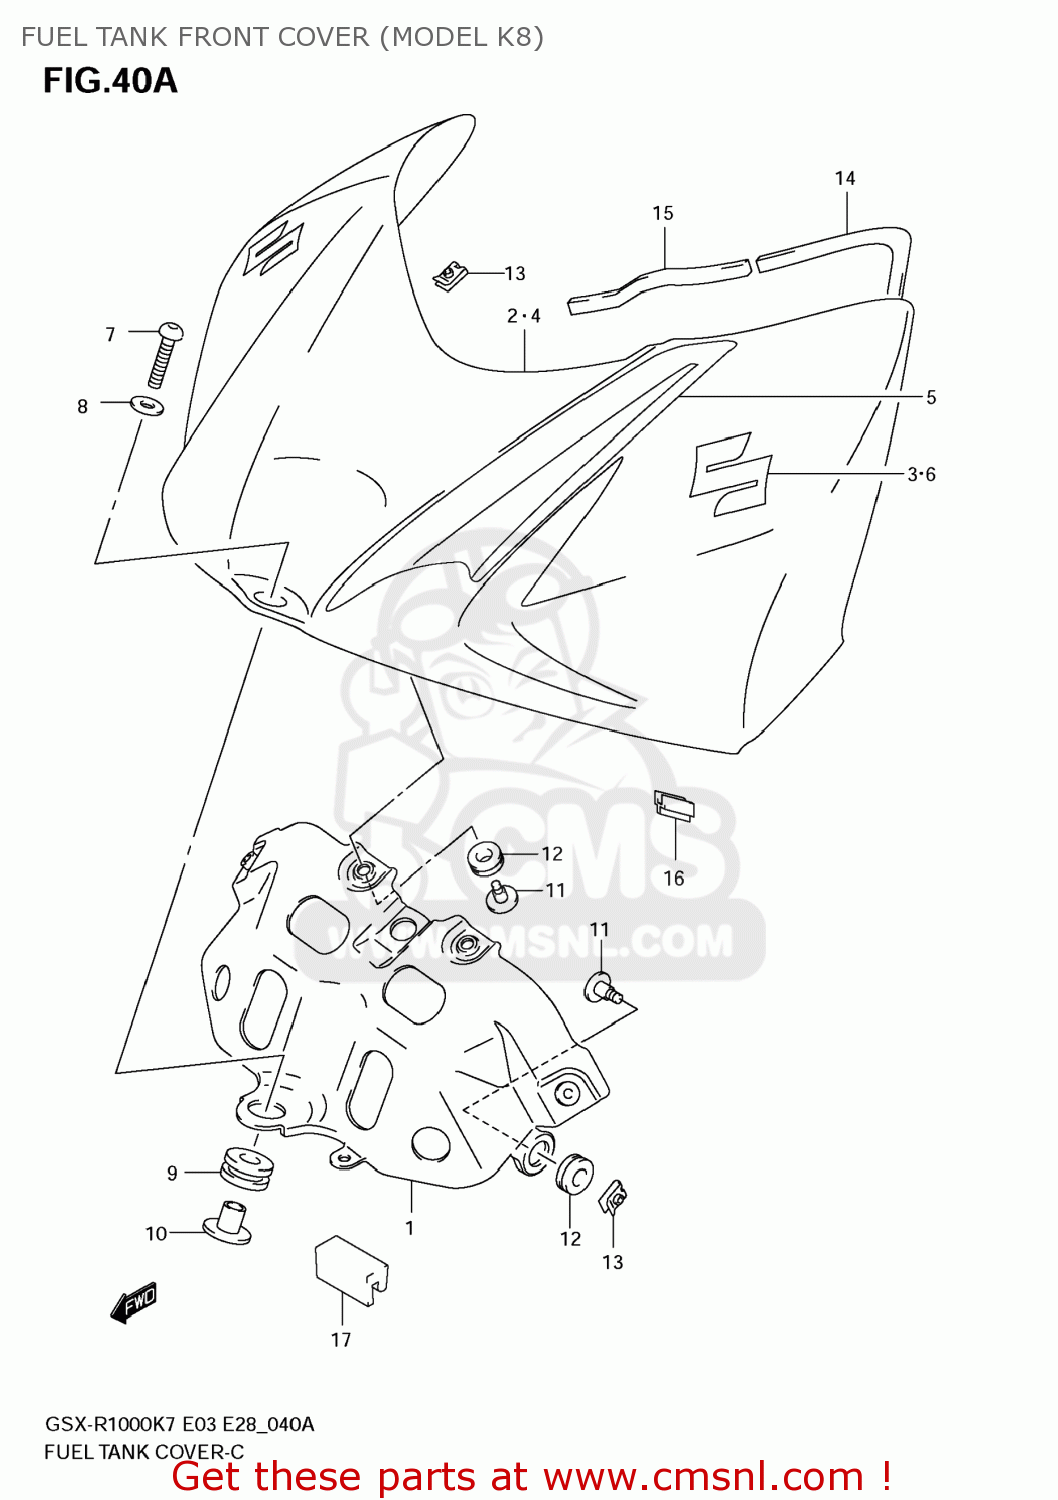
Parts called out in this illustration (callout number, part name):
1	BRACKET,FUEL TANK FR
2	COVER,FUEL TANK FR
3	EMBLEM,S
4	COVER,FUEL TANK FR
5	TAPE SET,FUEL TANK COVER
6	EMBLEM,S
7	BOLT(8X37)
8	WASHER(8.5X20X1.6)
9	CUSHION
10	SPACER(8.6X12X16.1)
11	SCREW(5X16.4)
12	CUSHION
13	NUT
14	CUSHION,FUEL TANK COVER
15	CUSHION,TANK COVER
16	CUSHION,FUEL TANK COVER
17	MOLDING
